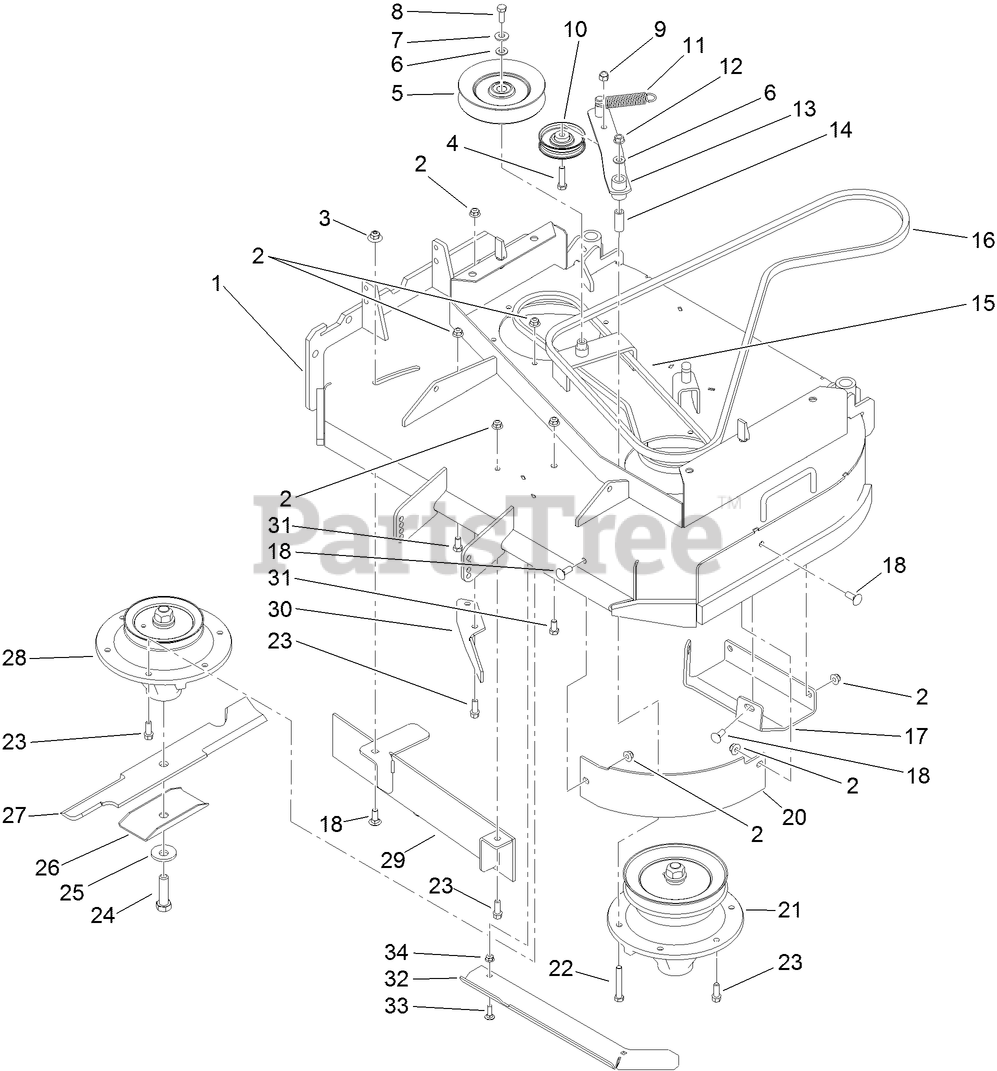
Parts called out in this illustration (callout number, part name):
1	DECK AND DECAL ASM
2	NUT-HF, NI
3	NUT-FLANGE, NI
4	SCREW-HH
5	PULLEY-IDLER
6	WASHER-FLAT
7	WASHER-BELLEVILLE
8	SCREW-HH
9	NUT-LOCK, NI
10	PULLEY-IDLER
11	SPRING-EXTENSION
12	NUT-HF
13	IDLER ARM ASM
14	SLEEVE-PIVOT, IDLER
15	BELT-V
16	BELT-DRIVE, PTO
17	PLATE-SKID
18	BOLT-CARR
20	BAFFLE-FRONT, LH
21	SPINDLE ASM
22	SCREW-HH
23	SCREW-HWH
24	SCREW-BLADE
25	Washer-Blade Bolt, Heavy
26	STIFFENER-BLADE
27	BLADE-18IN, HI FLOW
28	SPINDLE ASM
30	BAFFLE-DISCHARGE
31	SCREW-HH
32	EXTENDER-DECK
33	BOLT-CARR
34	NUT-HF, NI
